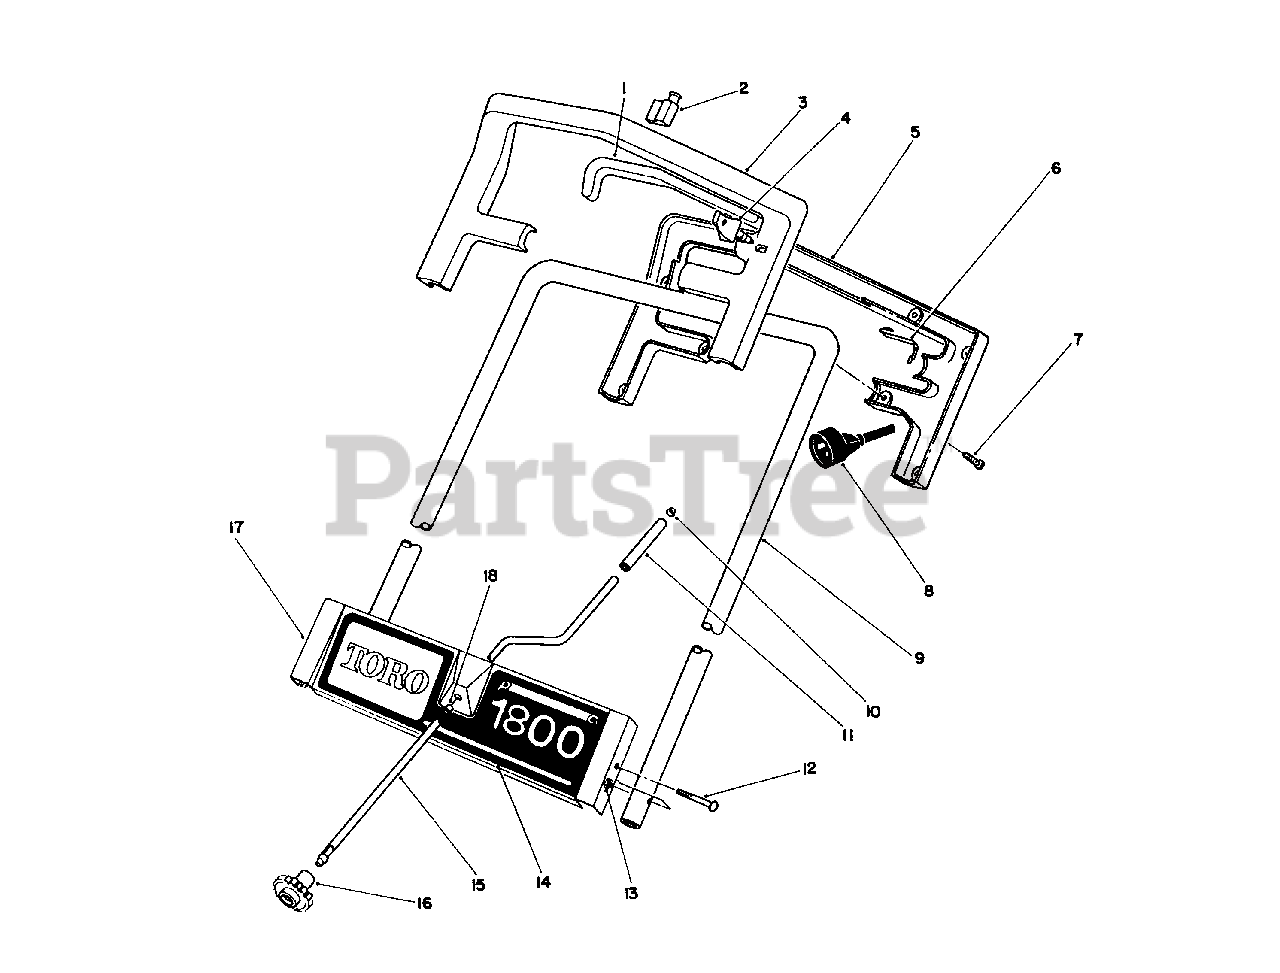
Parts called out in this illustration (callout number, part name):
1	Bar-Switch
2	Switch
3	Handle-Upper Control
5	Handle-Lower Control
6	Spring-Interlock
7	Screw-Pan Hd. Form.
8	Cord-Supply
9	Tube-Upper Handle
10	Push Nut
11	Sleeve-Chute Crank
12	Hex Hd. Mach. Screw
14	Decal-Escutcheon
15	Rod-Chute Crank
16	Gear-Chute Crank
17	Plate-Escutcheon
18	Bushing-Snap In
